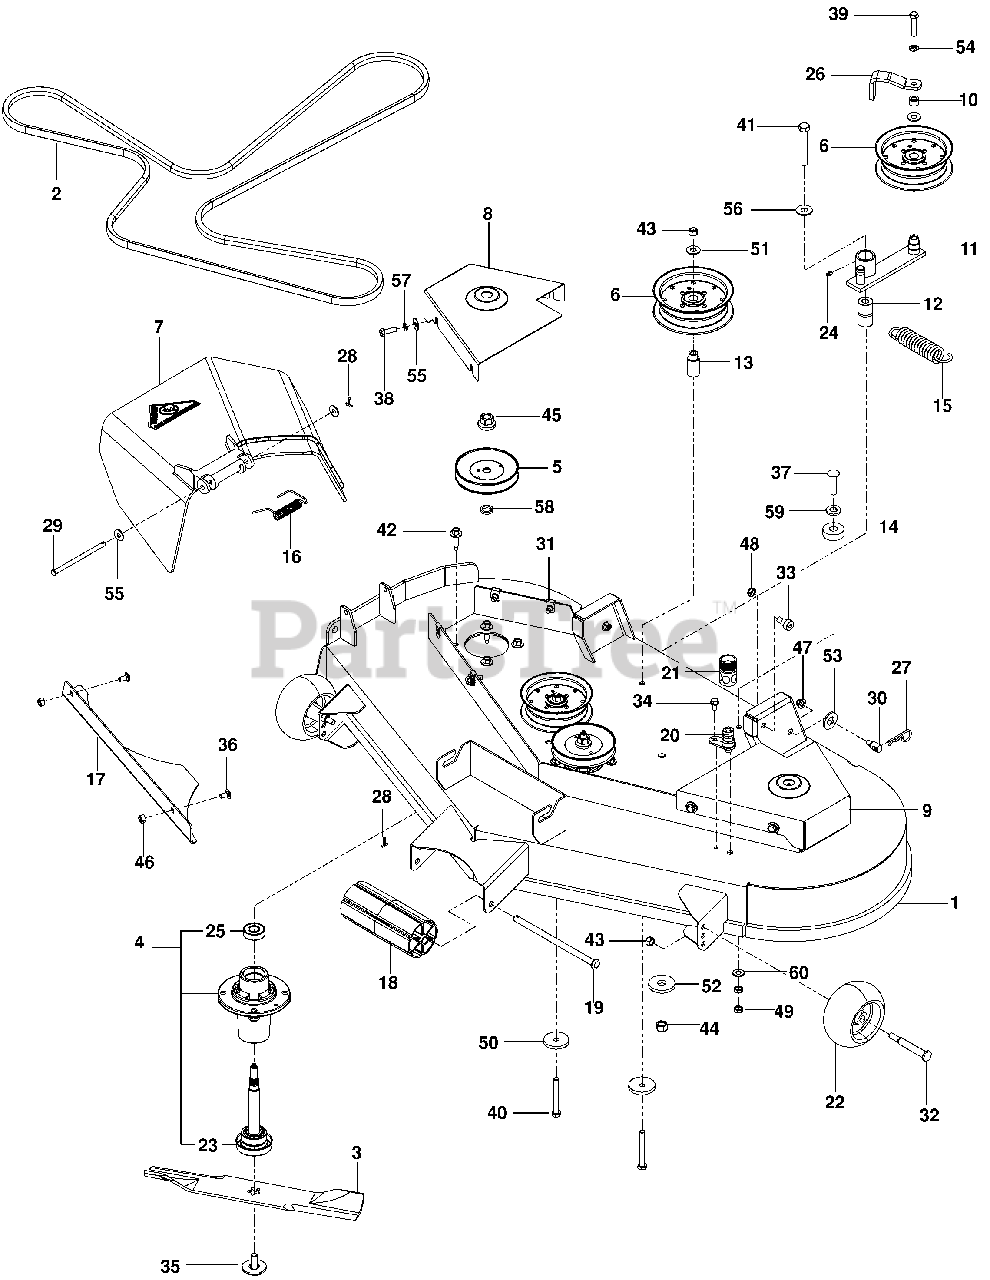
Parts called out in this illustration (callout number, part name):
2	BELT, DECK
3	BLADE, 16-1/4"
4	MANDREL ASM, CAST IRON
5	PULLEY MANDREL
6	PULLEY, IDLER
7	DISCHARGE CHUTE 48"
11	IDLER ARM
12	PIVOT BUSHING
13	IDLER BUSHING
14	ISO-MOUNT BUSHING
16	SPRING - TORSION
18	NOSE ROLLER 48"
19	ROD.ROLLER.NOSE.NARROW.48"
20	PORT.WASHOUT
21	COUPLING.QUICK CONNECT
23	SHAFT ASM MANDREL
24	ZERK
25	BEARING
26	GUIDE, BELT
27	HAIRPIN #4
28	COTTER PIN 1/8 X 3/4
29	PIN-CLEVIS 5/16 DIA X 5.19 ZD
30	STUD.FASTNER.W/ANTI-ROTATE
31	U-CLIP 5/16-18 NUT RETAINER
32	BOLT.SHOULDER.3/8-16X3-5/8
33	SB 3/8-16 X 3/8 SKT HD ZD
34	BOLT 1/4-20 X 1/2 HWST
35	BOLT.WASHER.ASM.7/16-2
36	CARRIAGE BOLT 5/16C X 5/8"
37	RHSNB 3/8-16X1-3/4
38	HCS 5/16C X 1
39	HCS 3/8-16 X 1 3/4 GR5
40	HCS 3/8C X 3
41	HCS 3/8-16 X 3-1/4 GR5 ZD
43	NUT 3/8-16 NYLOC
44	NUT 1/2-13 HEX NYLOC ZD
46	NUT 5/16 NYLOC
47	5/16-18 NYLOC FLANGE NUT
48	NUT HEX 3/8-16 NYLON, THIN
49	NUT 3/8-16 HEX JAM
50	SPINDLE WASHER
51	WASHER 3/8 FLAT
52	WASHER, SUPPORT
53	WASHER 5/8 FLAT
54	SLW 3/8 STD
55	WASHER 5/16 FLAT
56	WASHER 1/2 FLAT
57	WASHER 5/16 LOCK
59	WASHER 1/2" FLAT
60	WASHER 3/8 SAE FLAT
